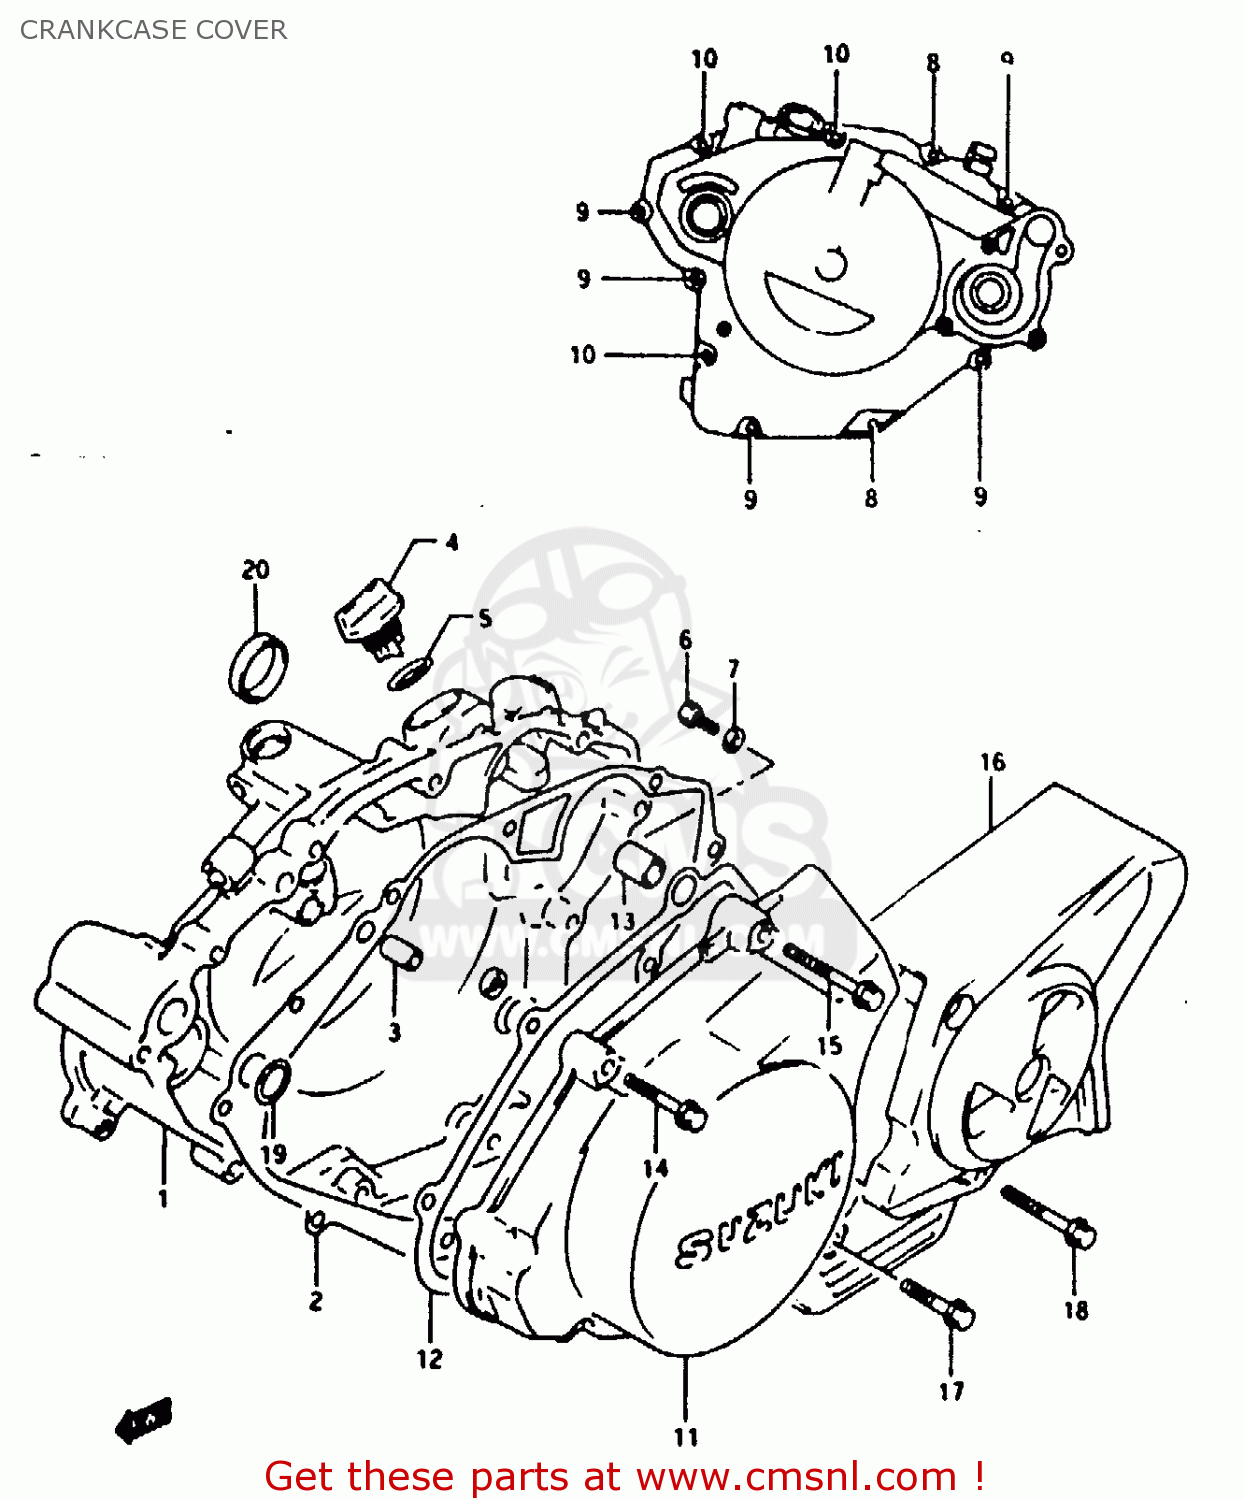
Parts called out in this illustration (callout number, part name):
1	COVER, CLUTCH
2	GASKET,CLUTCH COVER (NAS)
3	PIN
4	PLUG,OIL FILLE
5	O RING
6	SCREW(6X10)
7	GASKET(6.2X11X1) (NAS)
8	BOLT
9	BOLT
10	BOLT
11	COVER,MAGNETO
12	GASKET,MAGNETO COVER (NAS)
13	PIN
14	BOLT
15	BOLT
16	COVER,SPROCKET
17	BOLT
18	BOLT
19	O RING(D:1.9,ID:14.5)
20	PLUG,CLUTCH COVER KICK
